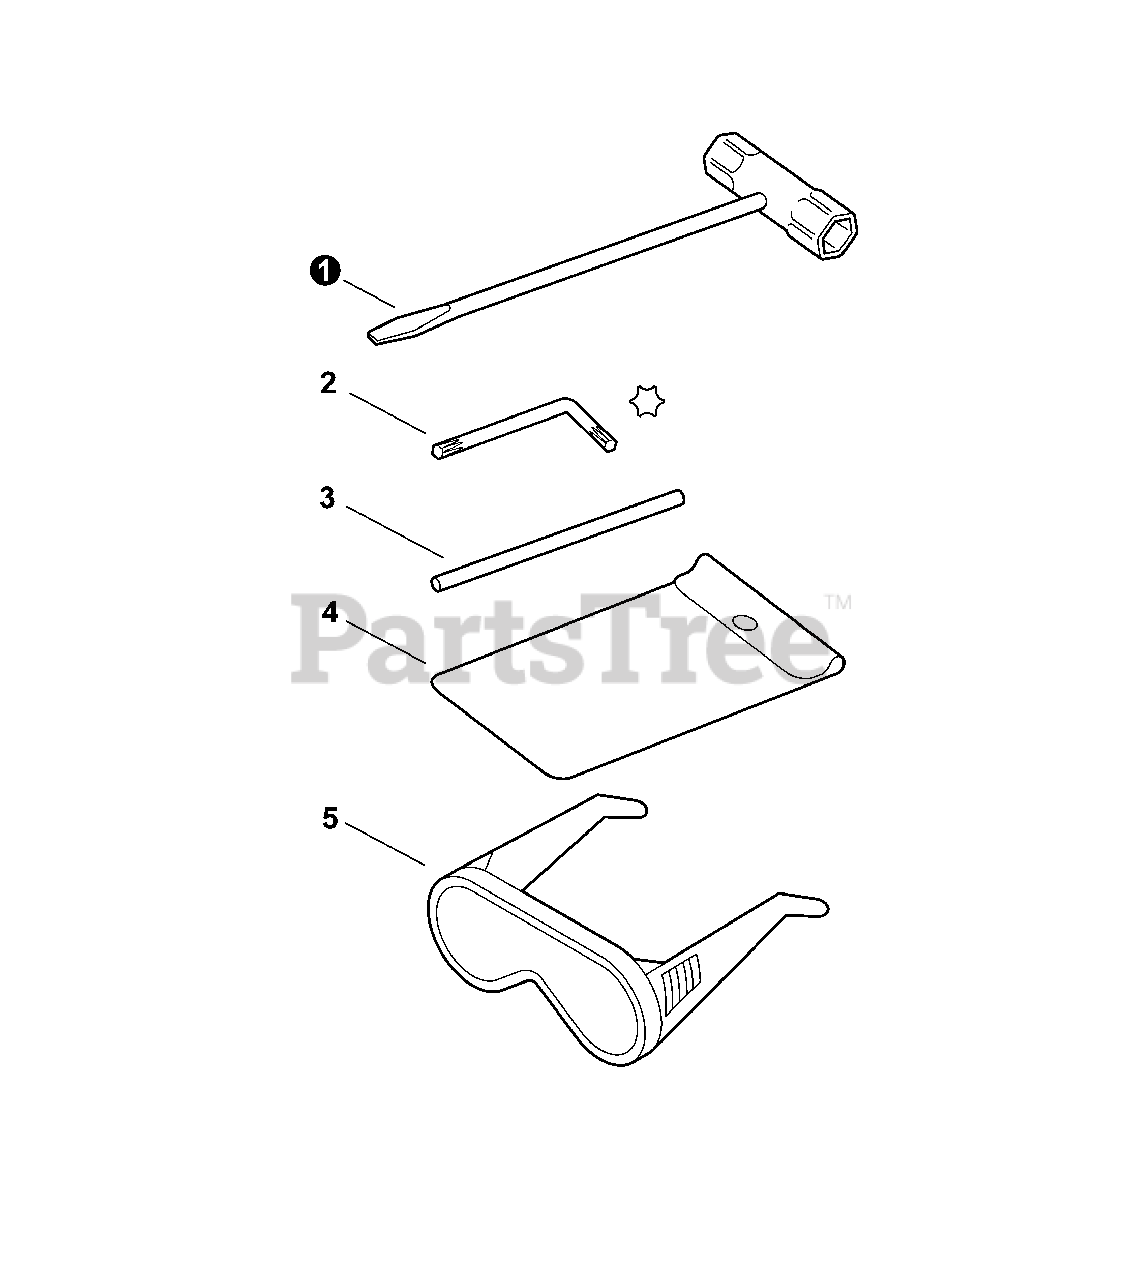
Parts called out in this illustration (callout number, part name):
1	T-WRENCH 17x-19 L200
2	WRENCH, T27 80×30
3	TOOL, LOCKING 5×120 MM
4	BAG, TOOL
5	GLASSES, SAFETY
